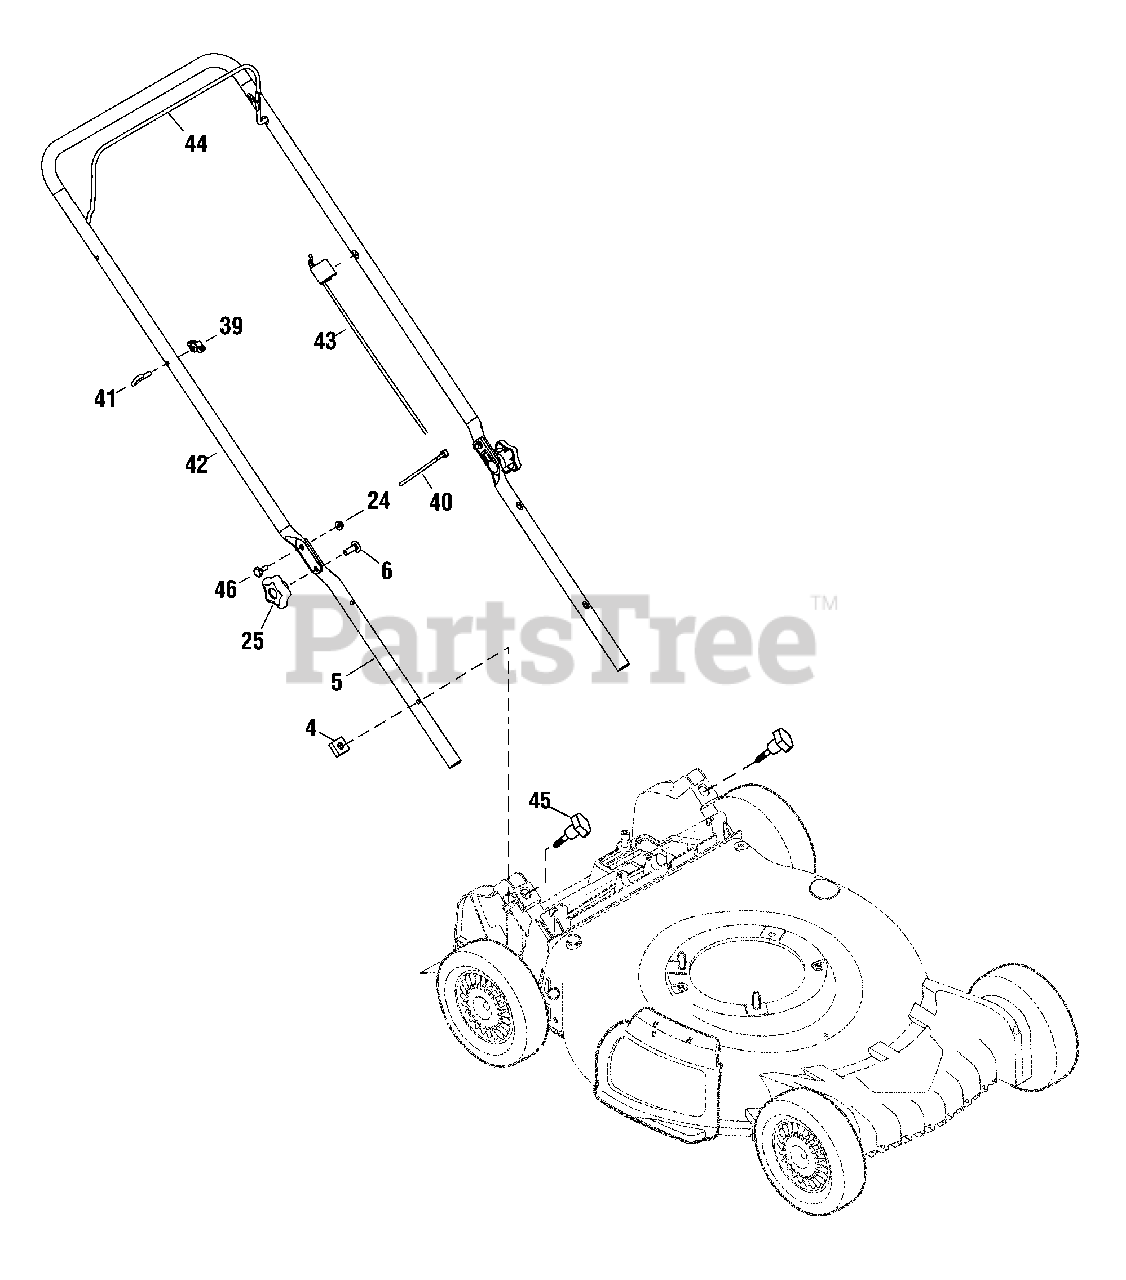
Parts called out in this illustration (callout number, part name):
4	NUT, Square, 1/4-20
5	HANDLE, Lower
6	BOLT, Carriage, 5/16-18 x 1, GR5
24	NUT, Nylock Flanged, 1/4-20
25	KNOB, Wing, 5/16-18
39	KNOB, 1/4-20
40	TIE, Self Lock
41	GUIDE, Rope
42	HANDLE, Upper
43	CABLE, OPC Engine Brake
44	BAIL, Blade Control
45	NUT, Wing
46	BOLT, Shoulder, 1/4-20
